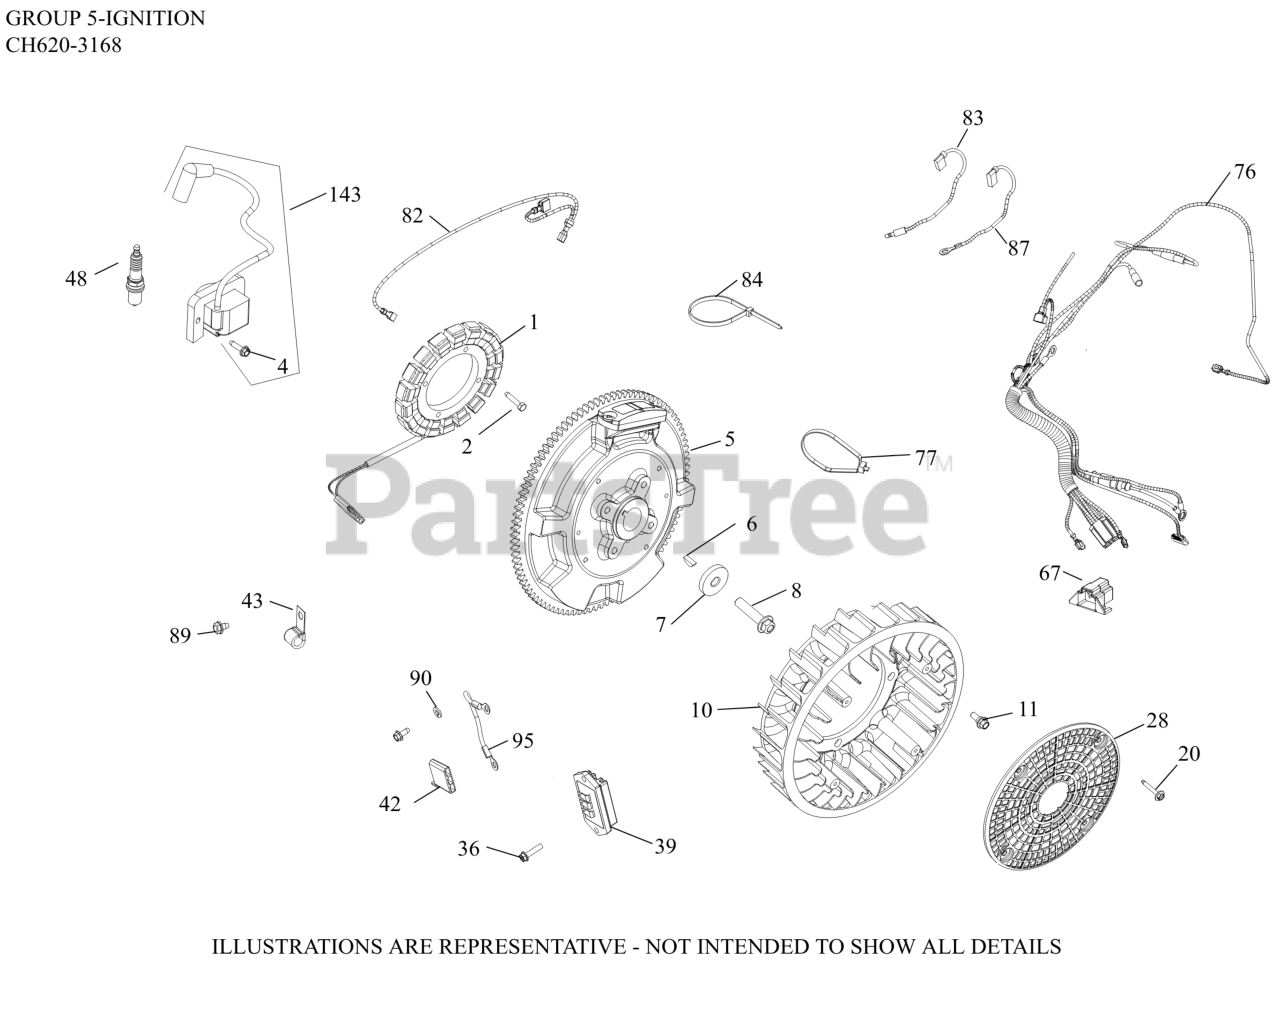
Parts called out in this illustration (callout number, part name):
1	KIT, 15 / 20 AMP STATOR
2	SCREW, THREAD FORMING
4	SCREW, THREAD FORMING
6	KEY, 3/16" X 5/8"
7	WASHER, FLAT 13/32"
8	SCREW, FLG M10X1.5X45-USE 25 086 361-S
10	FAN-USE 24 755 253-S
11	BOLT, SHOULDER
20	SCREW, SEMS DOG POINT
28	SCREEN,GRASS LOW PRFLE W/O HOLE
36	SCREW, HEX FLANGE HI-LO
39	REGULATOR/RECT 12/15A (41 403 10-S)
42	CONNECTOR
43	CLIP, CABLE
48	PLUG, SPARK (STD)
67	CONNECTOR
76	HARNESS WIRING ASSEMBLY
82	LEAD, DUPLEX
83	LEAD, OIL SENTRY
87	LEAD, 20/25 AMP B+
89	SCREW, THREAD FORMING
90	WASHER, LOCK
143	KIT, IGNITION MODULE
